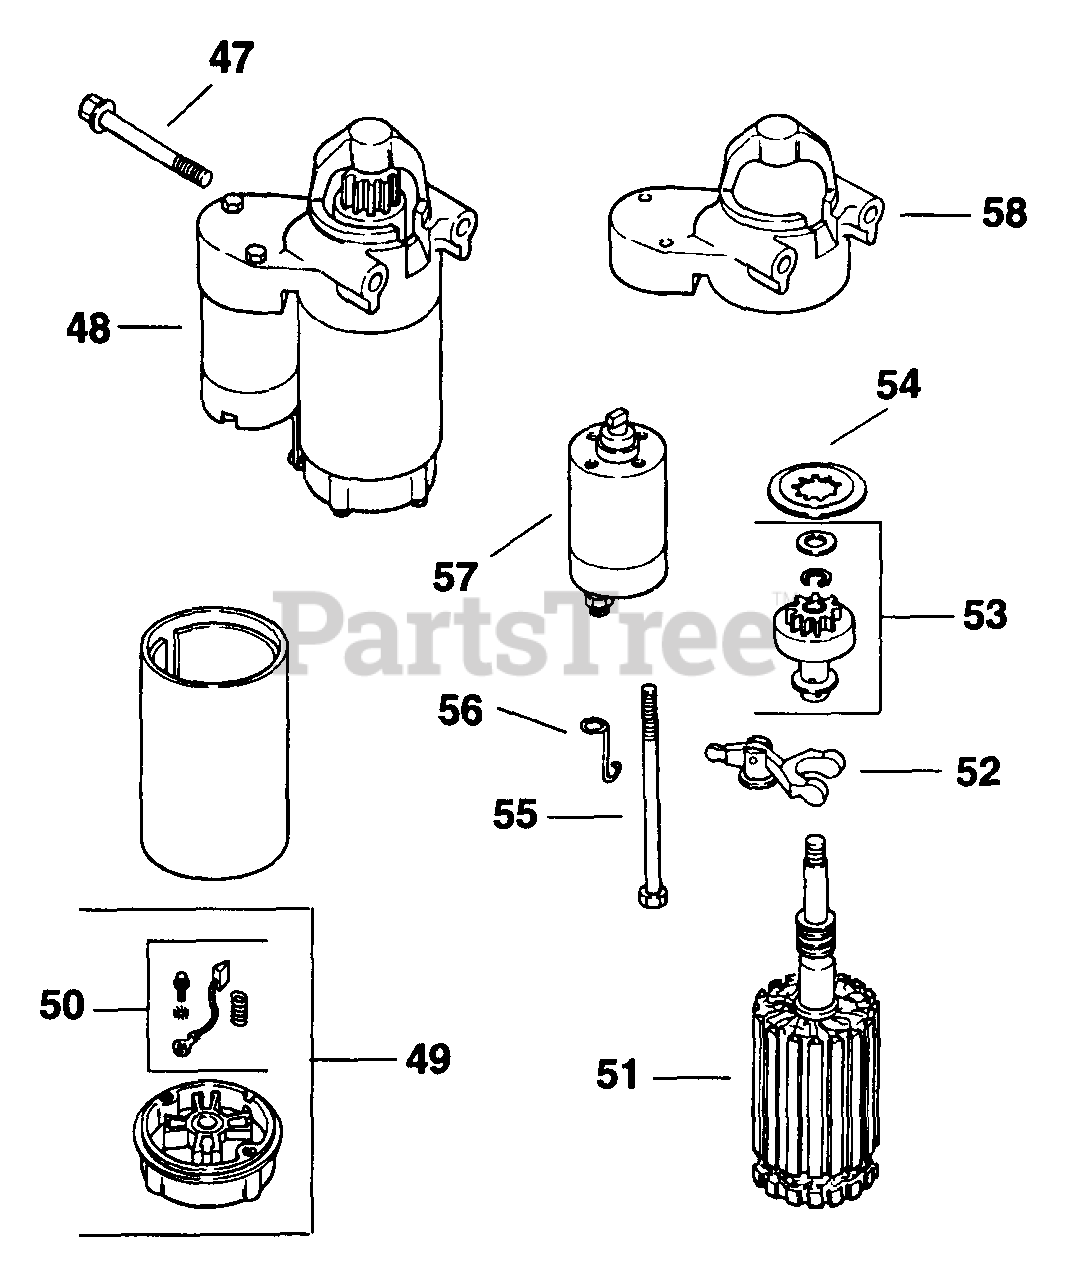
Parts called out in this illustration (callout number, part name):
47	Screw, hex. flange M8x1.25x75.6
48	STARTER ASSEMBLY - USE 25 098 11-S
49	CAP - DISCONTINUED
50	KIT - USE 82 755 28
51	ARMATURE - DISCONTINUED
52	LEVER - DISCONTINUED
53	KIT, DRIVE - DISCONTINUED
55	SCREW - DISCONTINUED
57	SOLENOID - UES 25 098 11-S
58	CAP - DISCONTINUED
